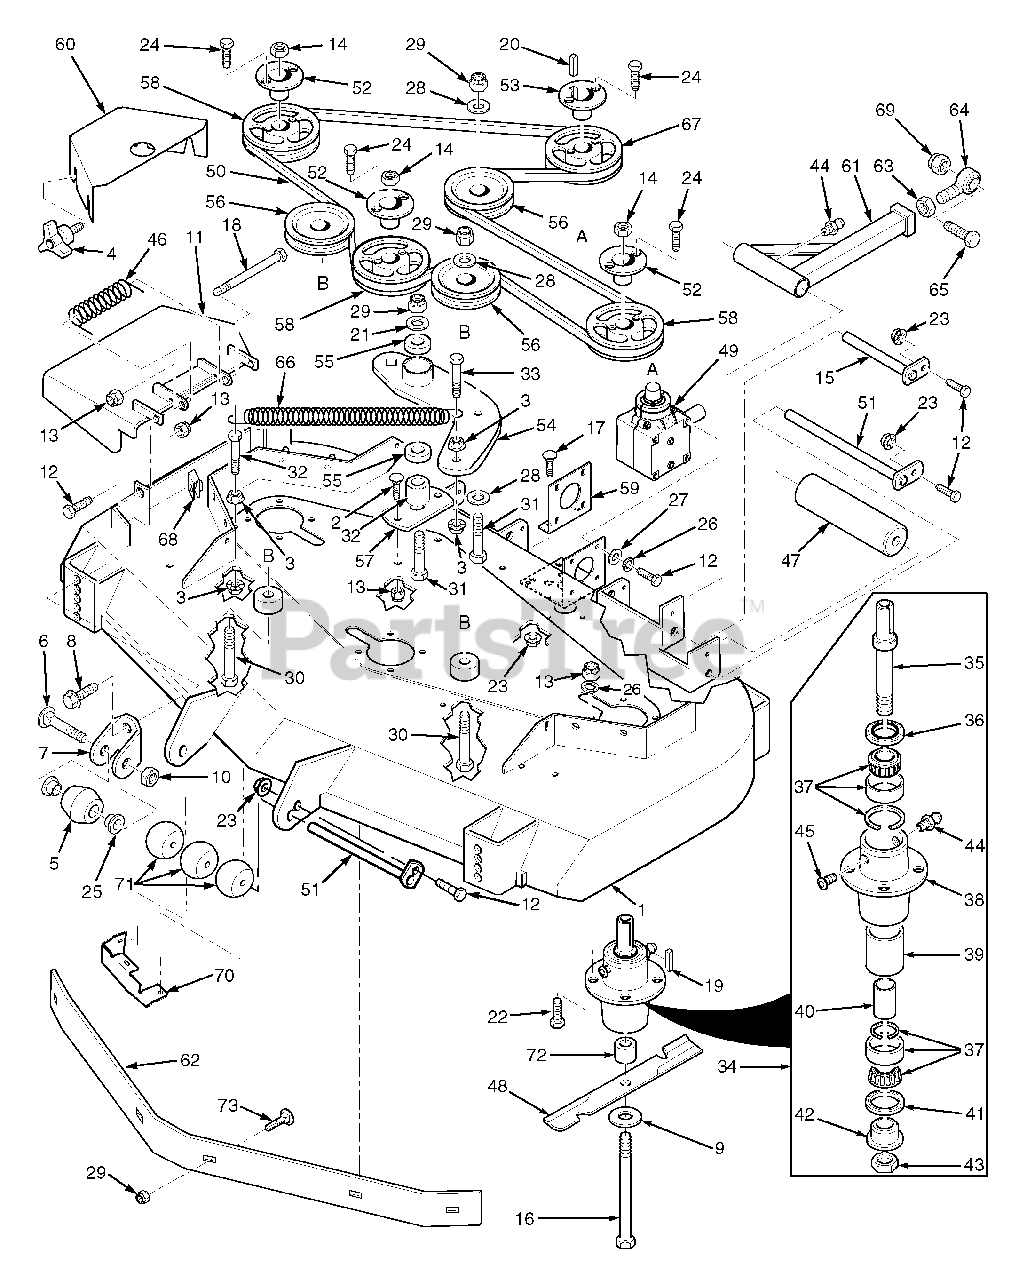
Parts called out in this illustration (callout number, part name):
1	Cutter Deck, 61" Advantage
1	Cutter Deck, 72" Advantage
2	Bolt, Carriage 5/16-18 x 1"
3	Nut, Hex Serrated Flange 3/8-16
4	Wing nut, 3/8-16
5	Anti-Scalp Wheel
6	Bolt, Carriage 3/8-16 x 4"
7	Anti-Scalp Wheel Bracket
8	Bolt, Hex Serrated Flange 3/8-16 x 1"
9	Flatwasher, 5/8" (.688 x 1.75 x .134)
10	Locknut, 3/8-16 Center Lock
11	Discharge Chute, 61" & 72" Adv.
12	Bolt, Hex Head 5/16-18 x 1.75" (Front)
13	Nut, Hex Elastic Stop 5/16-18
14	Nut, 5/8-11 UNC
15	Push Arm Shaft
16	Bolt, Hex Head 5/8-11 x 9.50"
17	Bolt, Carriage 5/16-18 x .75"
18	Bolt, Hex Head 5/16-18 x 4.75"
19	Key, 1/4 x 1/4 x 2"
20	Key, 1/4 x 1/4 x 1.25"
21	Flatwasher,3/8-.39 x .938 x .105 HD
22	Bolt, Hex Head 5/16-18 x 1-3/4" Grade 8
23	Nut, Hex Serrated Flange 5/16-18
24	Bolt, Hex Head 1/2-20 x 1" Grade 8
25	Bushing, .376 I.D. Oilite
26	Lockwasher, 5/16"
27	Flatwasher, 5/16" (.375 x .875 x .083)
28	Flatwasher, 3/8" (.391 x .938 x .105)
29	Nut, Hex Elastic Stop 3/8-16
30	Bolt, Hex Head 3/8-16 x 3.25"
31	Bolt, Hex Head 3/8-16 x 2.50"
32	Pivot, Idler - Short
33	Bolt, Hex Head 3/8-16 x 1.50" Grade 8
34	Spindle Assembly
35	Spindle Shaft
36	Seal, Top
37	Bearing Assembly
38	Spindle Housing
39	Spacer, Outside
40	Spacer, Inside
41	Seal, Bottom
42	Spindle Bushing, Bottom
43	Nut, Special 1 - 1/16-18
44	Grease Fitting
45	Relief Fitting, Tapered Spindle
46	Spring, Discharge Chute
47	Guide, Roller
48	Cutter Blade, 21.0" 61"
49	Gearbox Assembly, Deck Drive
50	Belt, Cutter Deck Drive, 61"
50	Belt, Cutter Deck Drive, 72"
51	Roller Shaft
52	Tapered Hub, 1-1/8" Bore
53	Tapered Hub, 1" Bore
54	Idler Arm, Cutter Deck
55	Bearings, Ball
56	Pulley, Idler
57	Base, Idler Pivot
58	Pulley, 6.35 O.D. - 61"
59	Mounting Plate, Gearbox
60	Belt Cover, 61"
61	Pusharm
62	Baffle, Custom Cut 61A
63	Nut, Hex Head 5/8-18 UNF
64	Rod End, 5/8" Male RH Thread
65	Bolt, Hex Head 5/8-11 x 4-1/2"
66	Spring, Cutter Deck
67	Pulley, 6.75 O.D. - 61"
68	U-Nut, 3/8-16
69	Nut, Hex Elastic Stop 5/8-11
70	Discharge Baffle 61"
71	Guide Roller
72	Spacer, Spindle
73	Bolt, Carriage 3/8-16 x 1"
04001.11	Bolt, Hex Head 5/16-18 x 150" (Rear)
